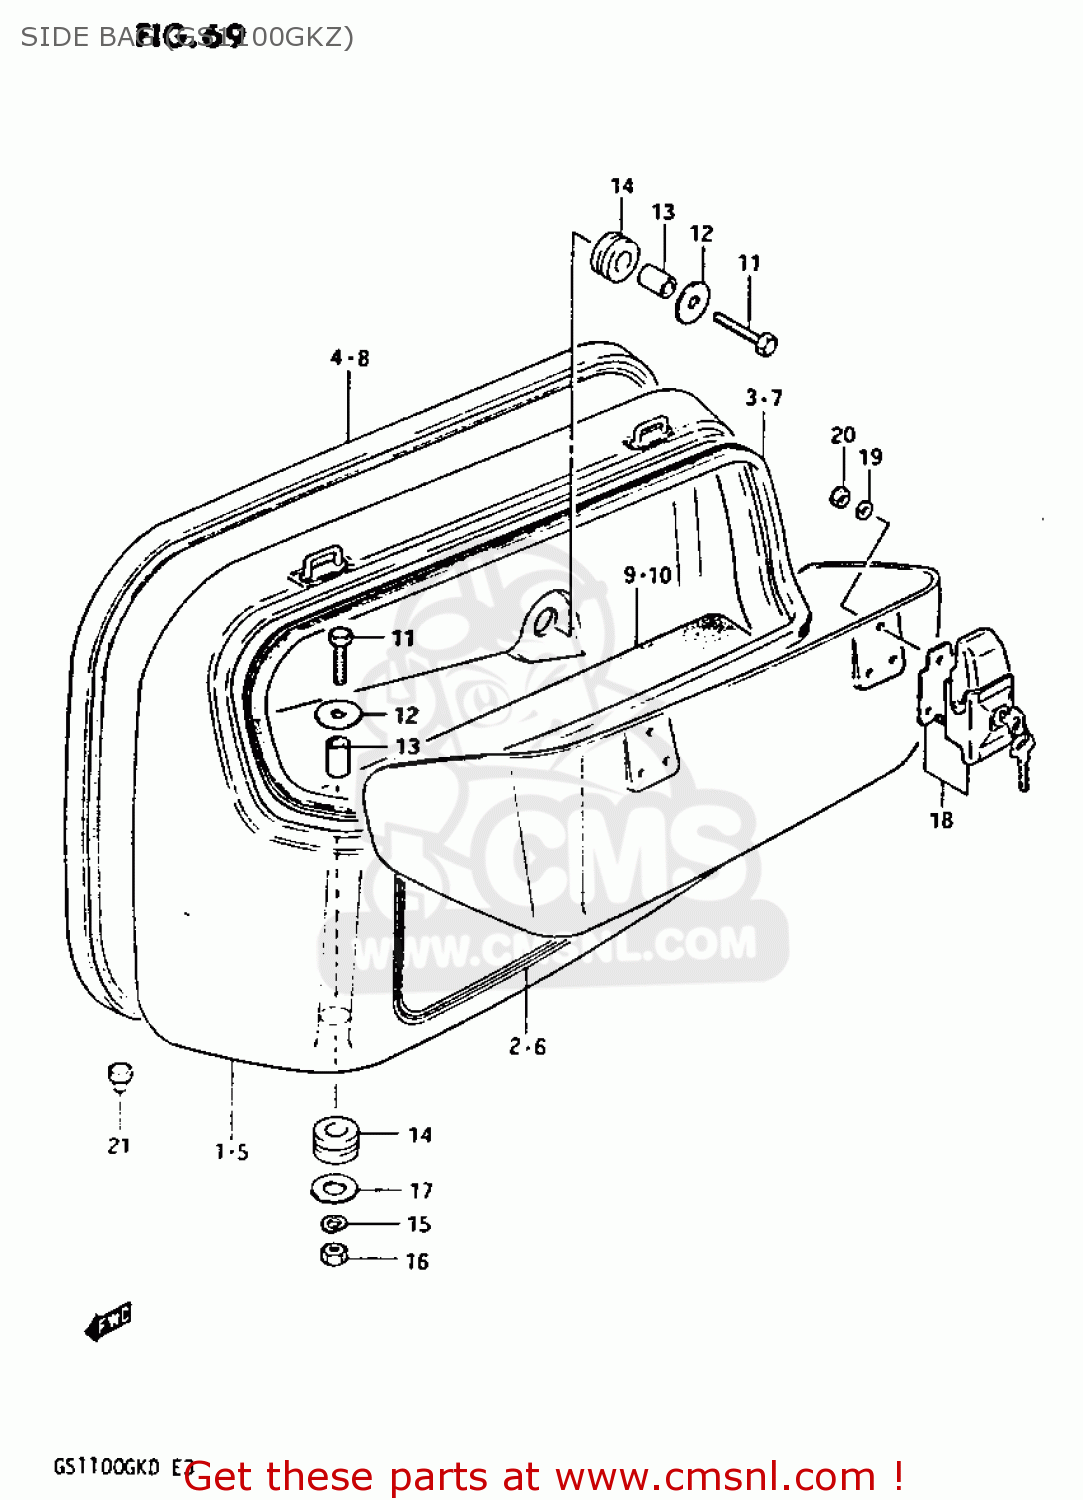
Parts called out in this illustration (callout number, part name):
1	SIDE BAG ASSEMBLY,RIGHT
2	TAPE SET,SIDE BAG,RIGHT
3	SEAL,TRAVEL TRUNK
4	MOLDING,SIDE BAG
5	SIDE BAG ASSEMBLY,LEFT
6	TAPE SET,SIDE BAG,LEFT
7	SEAL,TRAVEL TRUNK
8	MOLDING,SIDE BAG
9	CUSHION
10	CUSHION
11	BOLT
12	WASHER (6.5X29X1.6)
13	SPACER
14	CUSHION
15	WASHER,LOCK
16	NUT
17	WASHER (6.5X20X1.2)
18	LOCK,TRANK LID
19	WASHER 4MM
20	NUT 4MM
21	PLUG(OD:14)
